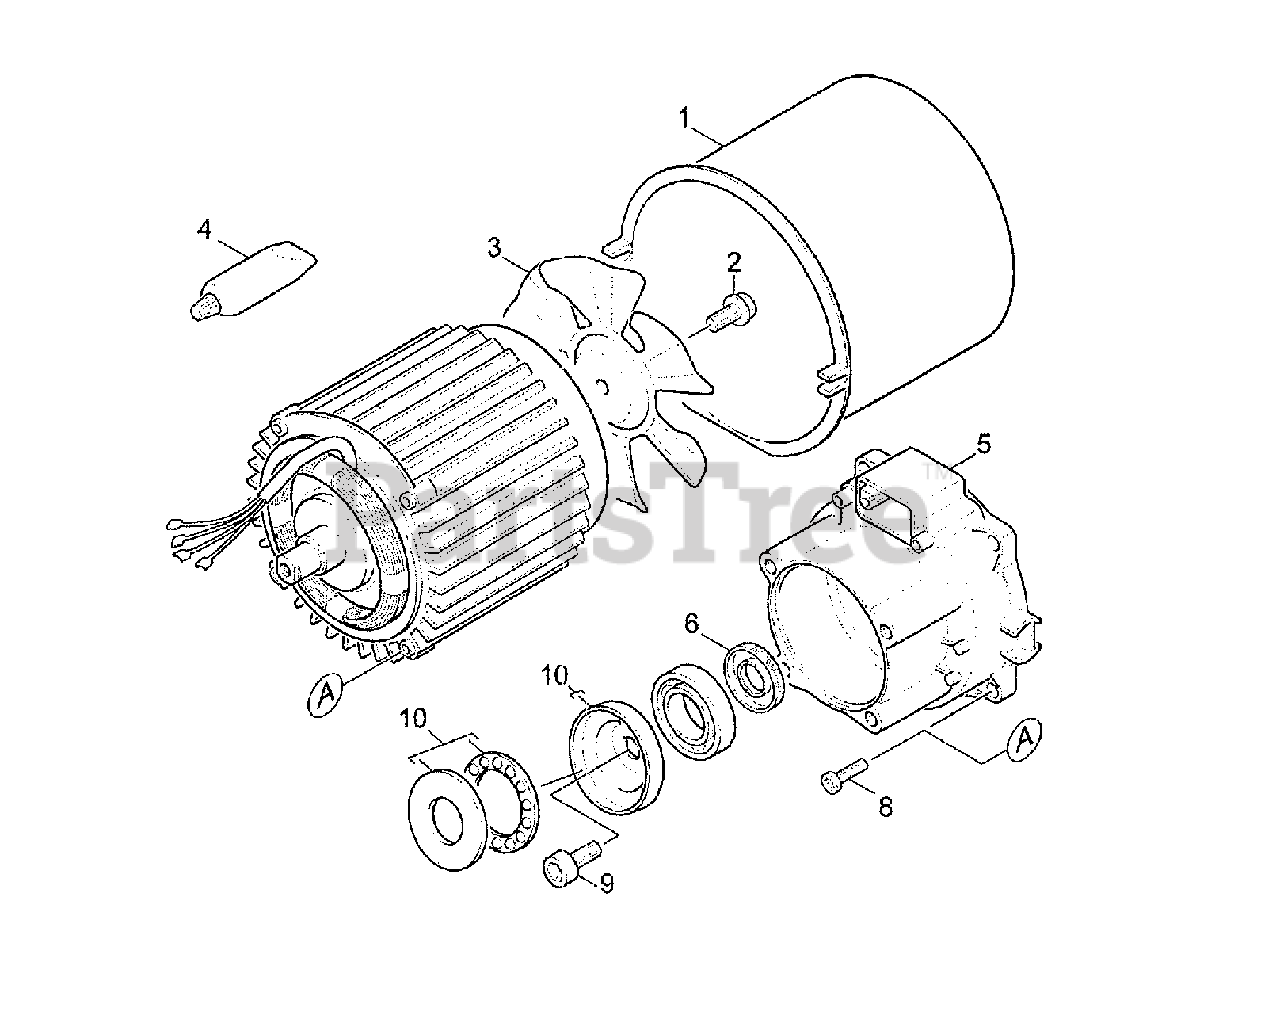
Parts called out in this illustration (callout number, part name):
1	Fan Housing
2	Hex Head Screw
3	Blower Wheel
6	Rotary Shaft Seal
10	Swash Plate
